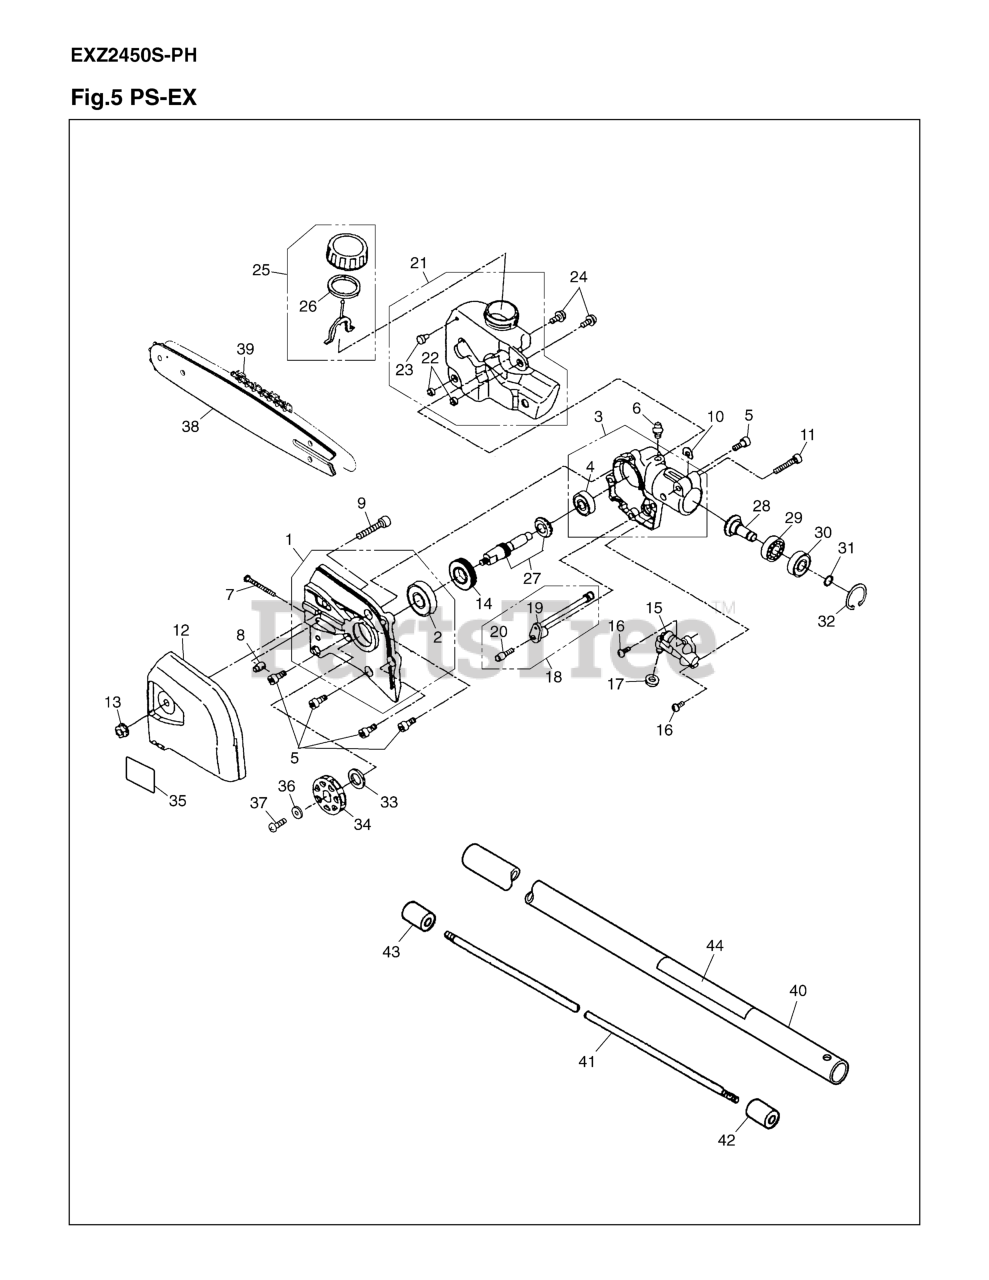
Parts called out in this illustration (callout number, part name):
1	GEAR CASE COMP-L
2	BEARING
3	GEAR CASE COMP-R
5	BOLT
6	FITTING, GREASE
7	SCREW
8	NUT
9	BOLT
10	SHIM
12	CHAIN COVER
13	NUT
14	GEAR, WORM
15	OIL PUMP ASSY
17	GASKET
18	OIL PIPE ASSY
19	OIL PIPE
20	FILTER
21	OIL TANK ASSY
22	COLLAR
23	VALVE
24	SCREW
25	CAP ASSY, OIL
26	GASKET, OIL CAP
27	GEAR SHAFT
28	BEVEL, PINION
29	BEARING
31	SNAP RING
32	SNAP RING
33	COLLAR
34	SPROCKET
35	LABEL
36	WASHER
37	SCREW
39	12
40	PIPE COMPLETE
41	SHAFT
42	SHAFT-JOINT
43	SPACER
44	NAMEPLATE
